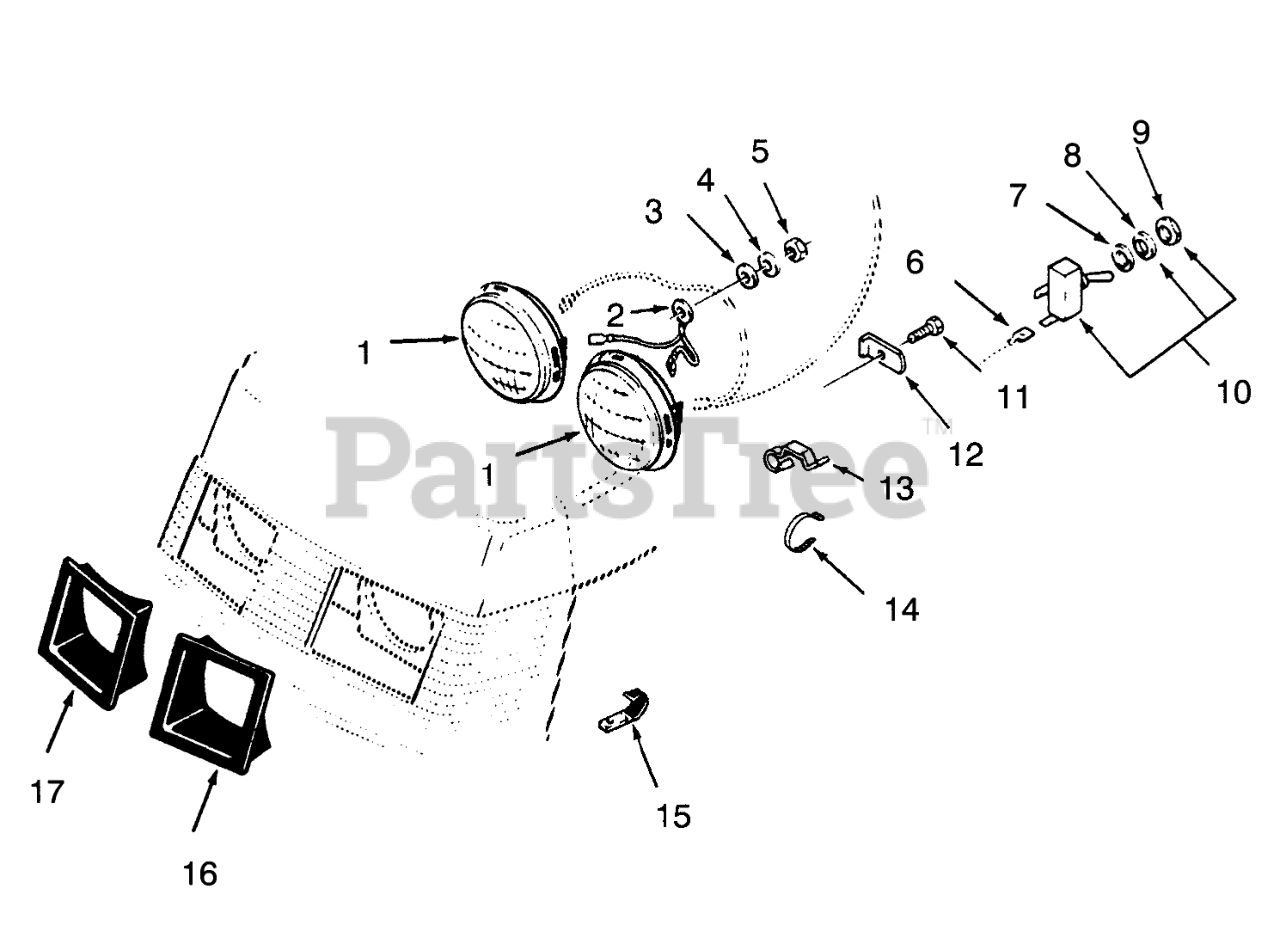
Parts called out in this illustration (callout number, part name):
1	HEADLAMP
2	LIGHT GROUND WIRE
3	WASHER-PLAIN
4	WASHER-LOCK, INTERNAL
5	NUT-LOCK, NI
6	Terminal
7	Washer
8	TAB-WASHER
10	SWITCH-LIGHTS
11	Bolt
12	LOCK-HEADLIGHT
13	CLIP-WIRE
14	PLASTIC TIE
15	CLIP
16	BEZEL-HEADLIGHT, LH
17	BEZEL-HEADLIGHT, RH
